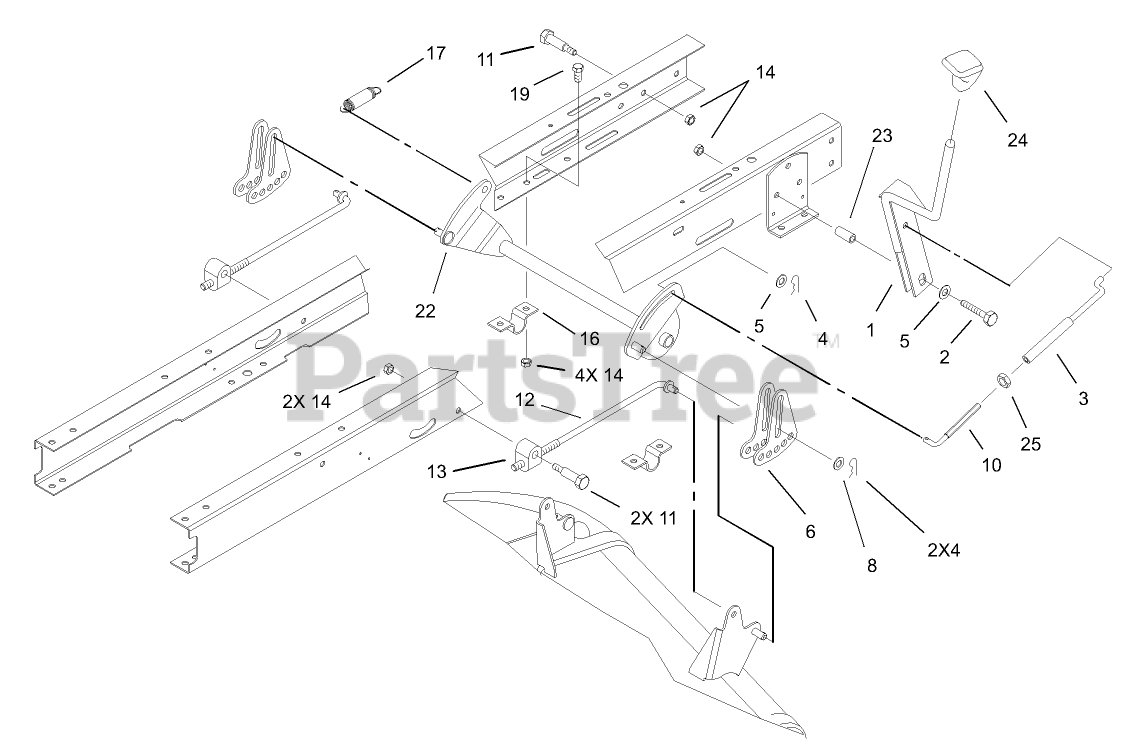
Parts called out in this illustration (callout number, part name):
2	SCREW-HH
3	HOC LINKAGE (WELDMENT)
5	WASHER-FLAT
6	LINK-ADJUSTING, HOC
8	WASHER-HARDENED
10	LINKAGE-HOC
11	SCREW-SHOULDER, HH
12	ROD-HANGER, REAR
13	TRUNNION-HOC
14	NUT-LOCK, NI
16	CLAMP-PIVOT, HOC
17	SPRING-EXTENSION
19	SCREW-HH
22	HOC PIVOT ASM (BLACK)
23	SPACER
24	KNOB-SHIFT
25	NUT-JAM
